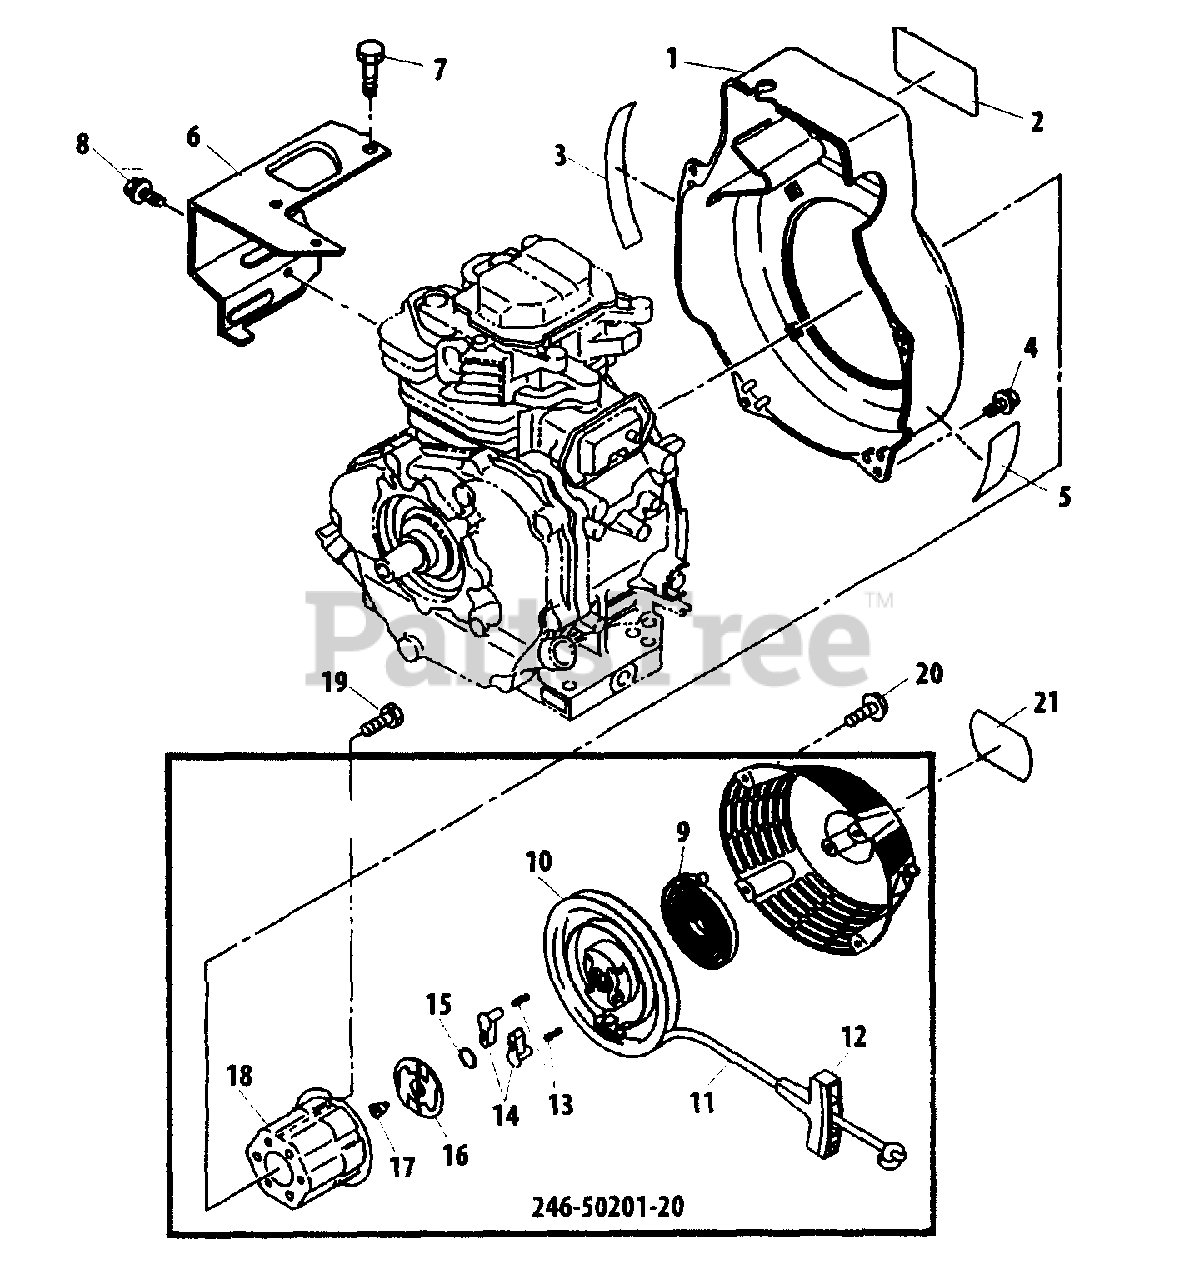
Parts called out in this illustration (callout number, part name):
1	CASE, FAN
2	LABEL - TRADE
3	LABEL
4	BOLT - FLANGE
5	LABEL - CAUTION
6	CYLINDER BAFFLE
7	BOLT
8	BOLT - FLANGE
9	RECOIL SPRING
10	REEL
11	ROPE
12	KNOB
13	SPRING, RETURN
14	RATCHET
15	SPRING, FRICTION
16	GUIDE
17	SCREW, SET
18	REEL, ROPE
19	BOLT
20	BOLT - FLANGE
21	LABEL - OHV
246-50201-20	STARTER ASSY
